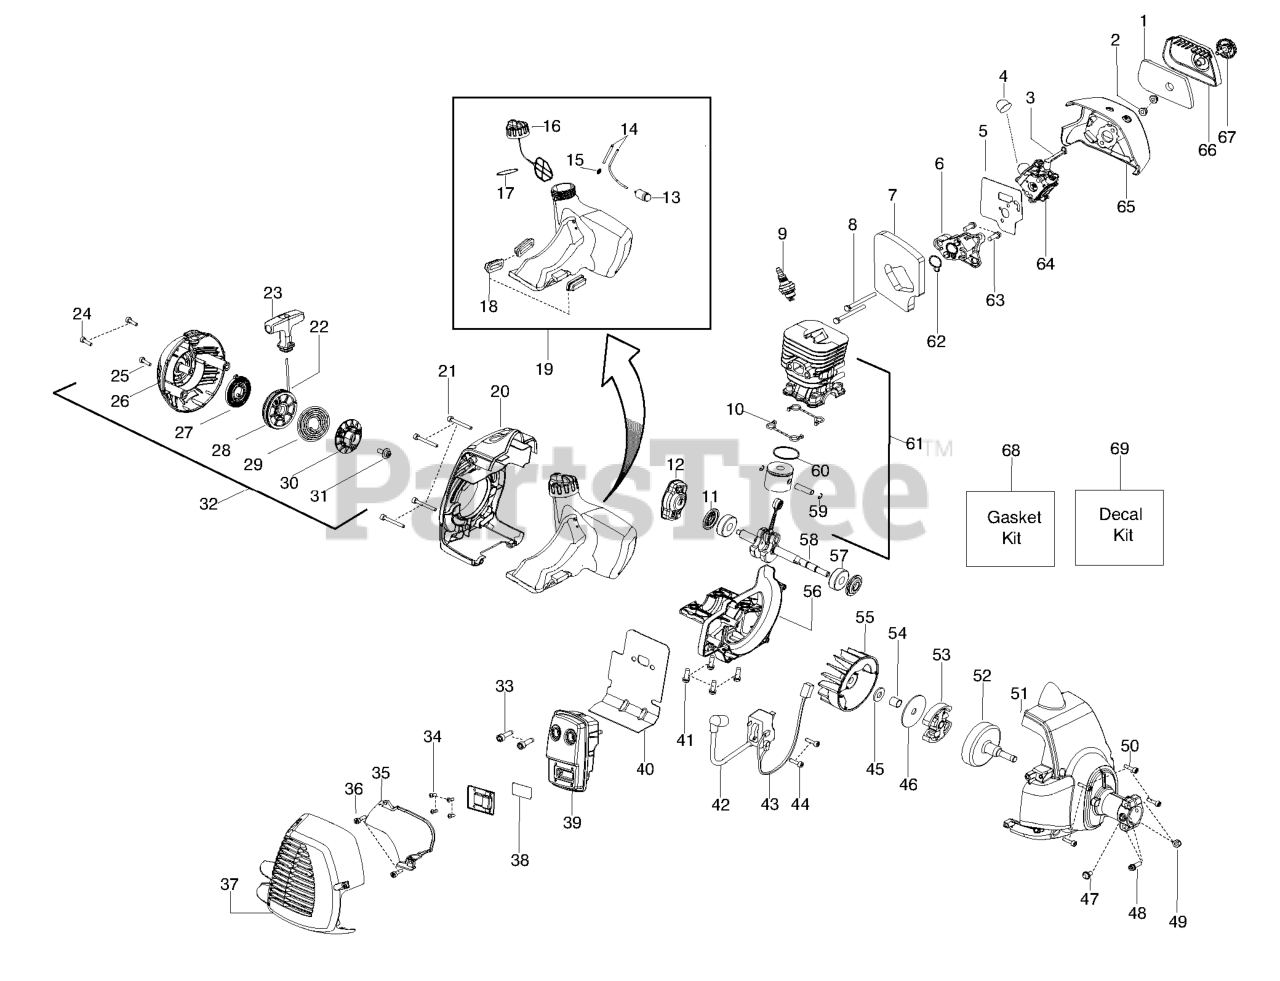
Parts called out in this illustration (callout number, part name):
1	FILTER AIRBOX
3	CHOKE LEVER
4	PURGE BULB ZAMA
5	KIT GASKET CARB 28CC
6	CARB ADAPTOR
7	KIT GASKET 28CC
8	BOLT CARB ADAPTOR
9	Plug-Spark (RCJ-6Y)
10	KIT GASKET 28CC
11	KIT GASKET 28CC
12	STARTER PAWL BRIDGE
13	FUEL PICK-UP ASSY
14	KIT-LINE(FUEL)
15	FUEL LINE FITTING
16	ASSY-CAP W/RETAINER
17	KIT GASKET 28CC
18	ISOLATOR FUEL TANK
19	KIT FUEL TANK HVA
20	KIT STARTER HSG HVA 128
22	KIT ROPE
23	HANDLE - STARTER
24	SCREW M5-0.8X30MM
25	SCREW M4 X 1.75 PT 16MM
26	KIT STARTER HSG HVA 128
27	KIT STARTER SPRING
28	KIT STARTER PULLEY
29	SPRING - DRIVER
30	DRIVER PULLEY
32	ASSY STARTER HSG HVA
33	BOLT MUFFLER
34	SCREW-6-19X5/16PLAST PA
35	SHIELD HEAT
36	SCREW M4 X 1.75 PT 16MM
37	KIT MUFFLER GUARD HVA
38	KIT SPARK ARRESTOR SCREEN
39	KIT MUFFLER LE28
40	KIT GASKET 28CC
41	SCREW-M5-0.8 X 25MM(TAP)
42	IGNITION MODULE MB45
43	ASSY MODULE LEAD WIRE
44	SCREW M4 X .70 TT 16MM
45	WASHER CLUTCH
46	WASHER-CLUTCH
47	Screw
48	Screw
49	LOCKNUT-HEX 10-24
50	SCREW M4 X .70 TT 16MM
51	Assy-Fan Housing
52	ASSY-CLUTCH DRUM
53	ASSY CLUTCH
54	SPACER FLYWHEEL
56	CRANKCASE CAST LE28
57	BEARING RADIAL BALL (6201)
58	ASSY CRANKSHAFT
59	WRIST PIN RET.
60	RING PISTON
61	KIT PISTON & CYLINDER
62	KIT GASKET 28CC
63	SCREW-M5-0.8 X 25MM(TAP)
64	KIT CARB
65	RP_AIR BOX
66	COVER-AIR BOX
67	KNOB ASSY AIRBOX COVER
68	KIT GASKET 28CC
